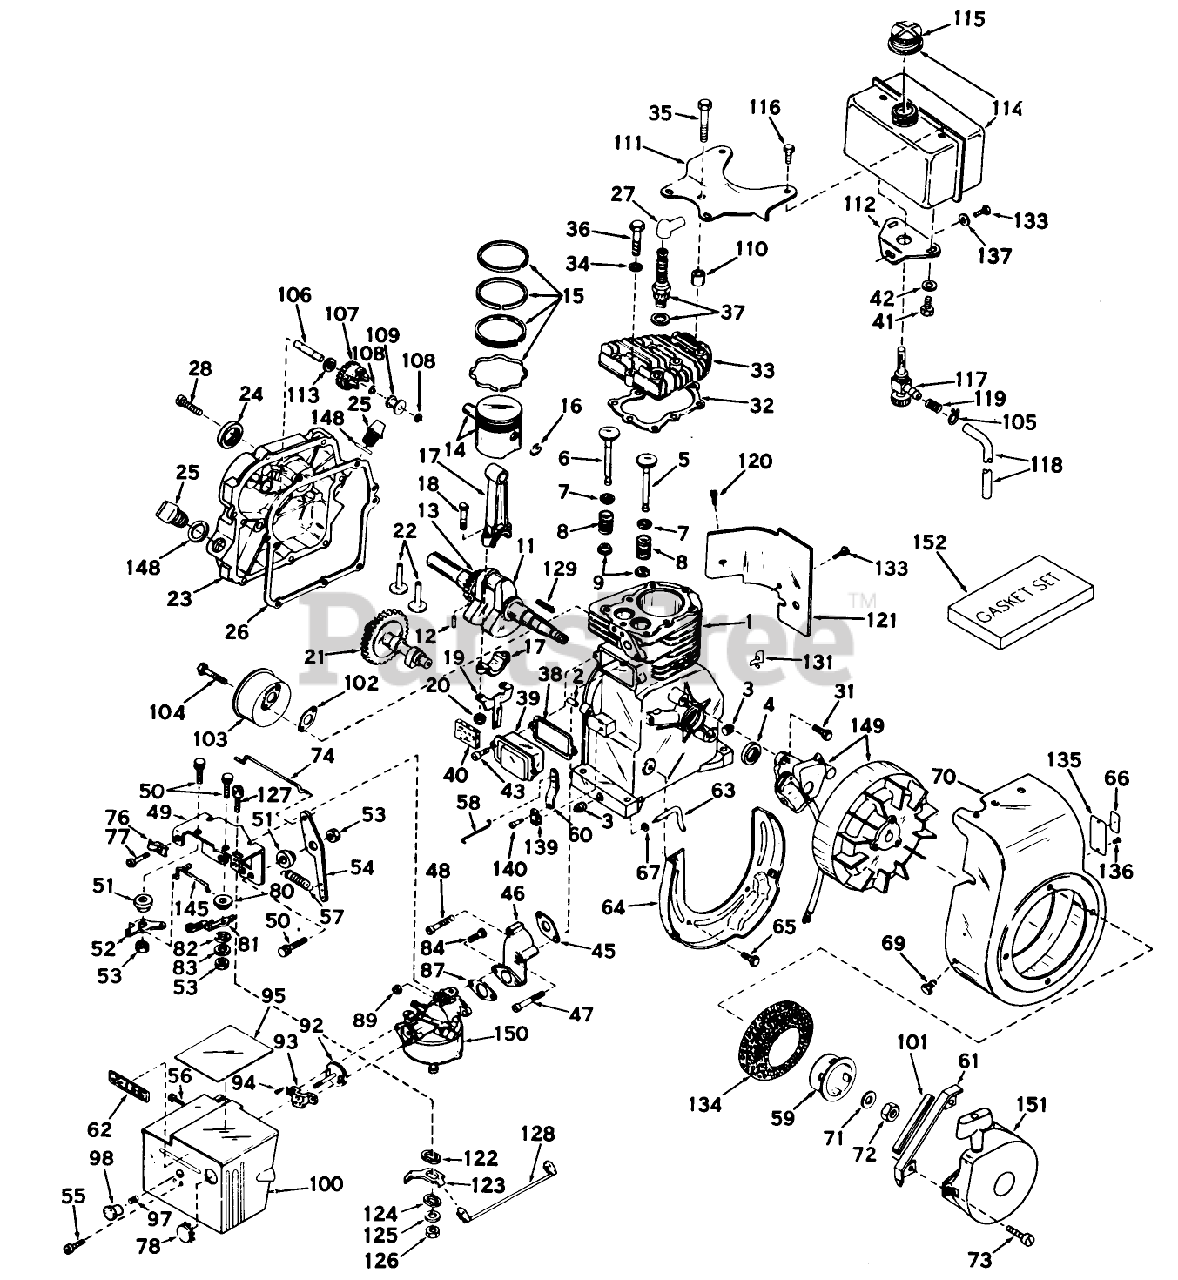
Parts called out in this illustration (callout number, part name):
1	Cylinder Assy., (Incl. Nos. 2, 3 4)
2	Pin-Dowel
3	Plug-Drain, Oil (SQH 1/4-18)
4	OIL SEAL
5	Valve, Intake (Incl. Ref. #38, 39 40) (Std.)
5	Valve, Intake(1/32"overs.)(Incl. Ref. 8, 9 10)
6	Valve, Exhaust (Standard)(Incl. Ref. 8, 9 10)
6	Valve, Exhaust (1/32" Overs.(Incl. Ref. 8, 9 10)
7	Cap-Upper Valve Spring
8	Spring-Valve
9	Cap-Valve, Spring
11	Crankshaft Assy. (Incl. Ref. 12 13)
12	Pin, Groove
13	Gear, Crankshaft
14	Piston Pin Assy. (Incl. 2 of No. 16)(Standard)
14	Piston Pin Assy. (Incl. 2 of No. 16)(.010 oversize)
14	53020 ADN. TO 28594
15	Piston Ring Set Std.
15	Piston Ring Set .010 O.S.
15	Piston Ring Set .020 O.S.
16	Ring-Retaining, Piston Pin
17	Rod Assy., Connecting (Incl. Ref. 18, 19 20)
18	Bolt, Connecting
19	53020/22 GIL.HYDRO
20	LOCKNUT
21	Camshaft
22	Lifter-Valve
23	Cover, Cylinder (Incl. Ref. 24 106)
24	Seal, Oil
25	Plug-Fill, Oil
26	Gasket-Cylinder Cover
27	Cover-Spark Plug
28	Screw
31	Screw
32	Gasket-Cylinder Head
33	CYLINDER HEAD
34	Washer
35	Screw
36	Screw
37	SPARK PLUG
38	Gasket Breather
39	Breather Assembly (Incl. Nos. 52 84)
40	Element-Breather
41	Screw
42	Washer
43	Screw
45	Gasket-Intake
46	INTAKE PIPE
47	Screw
48	Screw
49	Bracket, Speed Control
50	SCREW, HEX WASHER HD.
51	Bushing
52	Lever, RPM Adjusting
53	Nut
54	Lever, Bell Crank
55	752 SICKLE BAR MOWE
56	Screw, Rd. Hd. Sheet Metal
57	Spring-Extension
58	Jet-Main
59	Starter Cup
60	Lever-Governor
61	Guard, Starter
62	Decal, Choke
63	Rod-Governor
64	Baffle, Blower Hsg.
65	Screw (1/4-20x19/32)
66	Decal, Instruction
67	Washer-Flat
69	Screw
70	Housing,Blower
71	Washer
72	Hex Nut
73	Screw
74	Link, Bell Crank
76	Conduit
77	Screw (10-32 x 3/8)
78	Plug-Fill, Oil
80	Bushing Control Lever
81	Lever, Control
82	Washer
83	Washer, Flat
87	Gasket
89	Nut and Lock Washer (1/4-28)
92	Plate, Choke
93	Bracket-Choke
94	Screw, Phil. Fil. Hd. Sems
95	Decal, Operating
97	Spring, Compression
98	Knob, Choke
100	Capscrew
101	Seal, Snowguard
102	Gasket Exhaust
103	Muffler
104	Screw, Hex Hd. Cap
105	Clamp-Line, Fuel
106	Shaft-Governor
107	Governor Gear ASM
108	Ring-Retaining
109	Spool-Governor
110	pacer
111	Bracket, Fuel Tank-Upper
112	Bracket, Fuel Tank Lower
113	Washer-Flat
114	Tank Assy., Fuel (Incl. Ref. 112 115)
115	Cap, Fuel Tank
116	Screw
117	Fitting Shut-off, Fuel
118	Line-Fuel
119	Spring, Coil
120	Screw
121	Extension-Blower
122	Washer, Insulating
123	Terminal
124	Washer, Insulating
125	Washer, Flat
126	Nut
127	Screw, Hex Slotted Hd.
128	Wire, Ground
129	Key Flywheel
131	Clip-Wire
133	Screw
134	Screen, Air
135	IDENTIFICATION PLATE
136	DRIVE STUD
137	Washer
139	Clamp-Lever, Governor
140	Screw
145	Link, RPM Adjusting
148	Gasket
149	Magneto
150	Carburetor
151	Starter, Rewind
152	Gasket Set
